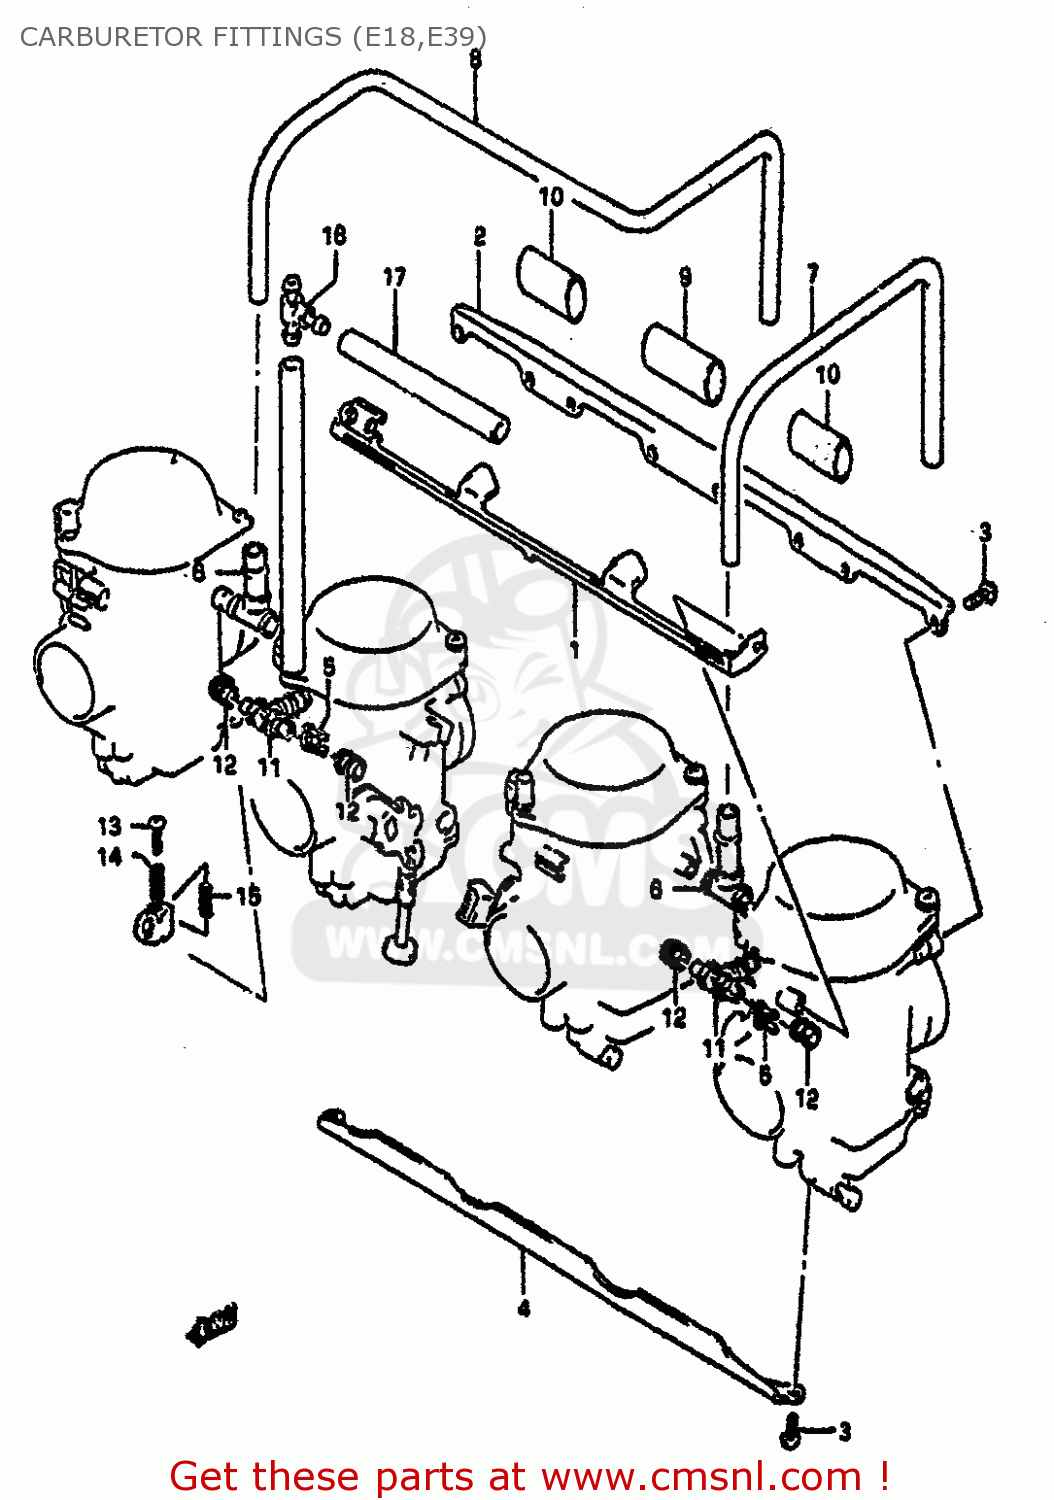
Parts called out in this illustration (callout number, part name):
1	LEVER
2	PLATE
3	SCREW
4	PLATE
5	HOLDER
6	HOSE
7	HOSE
8	HOSE
9	HOSE
10	HOSE
11	NIPPLE
12	SEAL
13	SCREW
14	SPRING
15	SPRING
16	NIPPLE
17	HOSE
18	LEVER,THROTTLE
19	SPRING
20	SHAFT ASSEMBLY
21	SEAL
22	GASKET,THROTTLE SHAFT (NAS)
23	SCREW
24	VALVE,THROTTLE(125)
25	GASKET,FLOAT CHAMBER (NAS)
26	JET,PILOT(30)
27	JET,NEEDLE(O-8)
28	O RING
29	JET,MAIN(122.5)
30	PLUG
31	FLOAT/NEEDLE VALVE ASSY
32	O RING
33	O-RING,NEEDLE VALVE
34	SCREW
35	SCREW
36	CAP
37	CLIP
38	SHAFT ASSEMBLY
39	RING
40	COVER,DIAPHRAGM
41	CAP,STARTER
42	HOSE
43	SCREW
44	SPRING
45	WASHER
46	HOLDER,GUIDE
47	SPRING
48	PLUNGER ASSY
49	JET,AIR(1.3)
